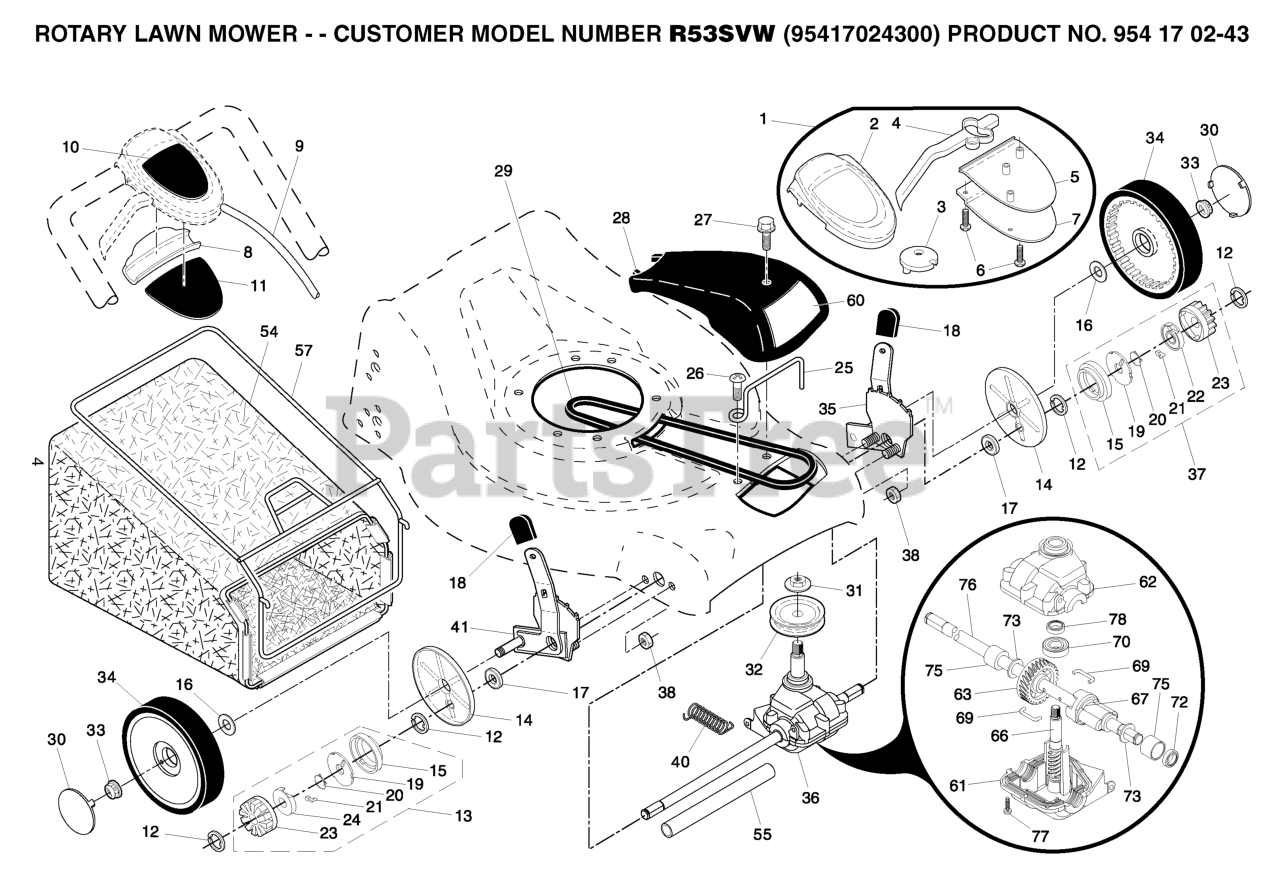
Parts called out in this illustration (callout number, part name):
2	COVER, DRIVE CONTROL, TOP
3	PULLEY.CAM.DRIVE.CONTROL.HV
4	LEVER, AUTOWALK DRIVE CONTROL
5	COVER, DRIVE CONTROL BOTTOM
6	SCREW, PHILLIPS HEAD 10 X 5/8
7	BRACKET, DRIVE CONTROL
8	CAP.DRIVE.CONTROL.BLACK.HI-VAC
10	DECAL, DRIVE
12	E-RING 7/16 RE
13	PINION ASSY, RH
14	COVER.DUST.WHEEL
15	SEAL.PINION
16	WASHER FLUT
17	BEARING, BALL
18	SELECTOR KNOB
19	DISC.DRIVE.21.EZ-WALK
20	SPRING, TORSION
21	PAWL.DRIVE.21.EZ-WALK
22	RETAINER.DRIVE.21.EZ-WALK.LT
23	GEAR, PINION
24	RETAINER, DRIVE, RH
25	KEEPER, BELT
26	BOLT.HEX.HDWSH.5/16-18X1.00
27	SCREW, HEX HD TAPPING #10-24 1
28	COVER.DRIVE.21.FWGD.GRAY
30	HUBCAP
31	FLANGED LOCKNUT 3/8-16 ZINC
32	PULLEY
35	KIT.ADJUSTER.ASM.EZ.LH
36	TRANSMISSION.21RD.FGDE
37	PINION ASSY, LH
38	LOCKNUT.NYLOC.1/4-20
40	SPRING, RETURN
41	KIT.ADJUSTER.ASM.EZ(169770).RT
55	DRIVESHAFT COVER
57	BAG FRAME
60	DECAL DRIVE COVER
61	LOWER CASE
62	UPPER CASE
63	GEAR.27.TEETH.WALK.MOWER
66	SHAFT INPUT (13056)
69	WIRE, FORMED (15966)
72	SEAL.OUTPUT.SHAFT
76	SHAFT OUTPUT (12198)
78	SEAL INPUT SHAFT
